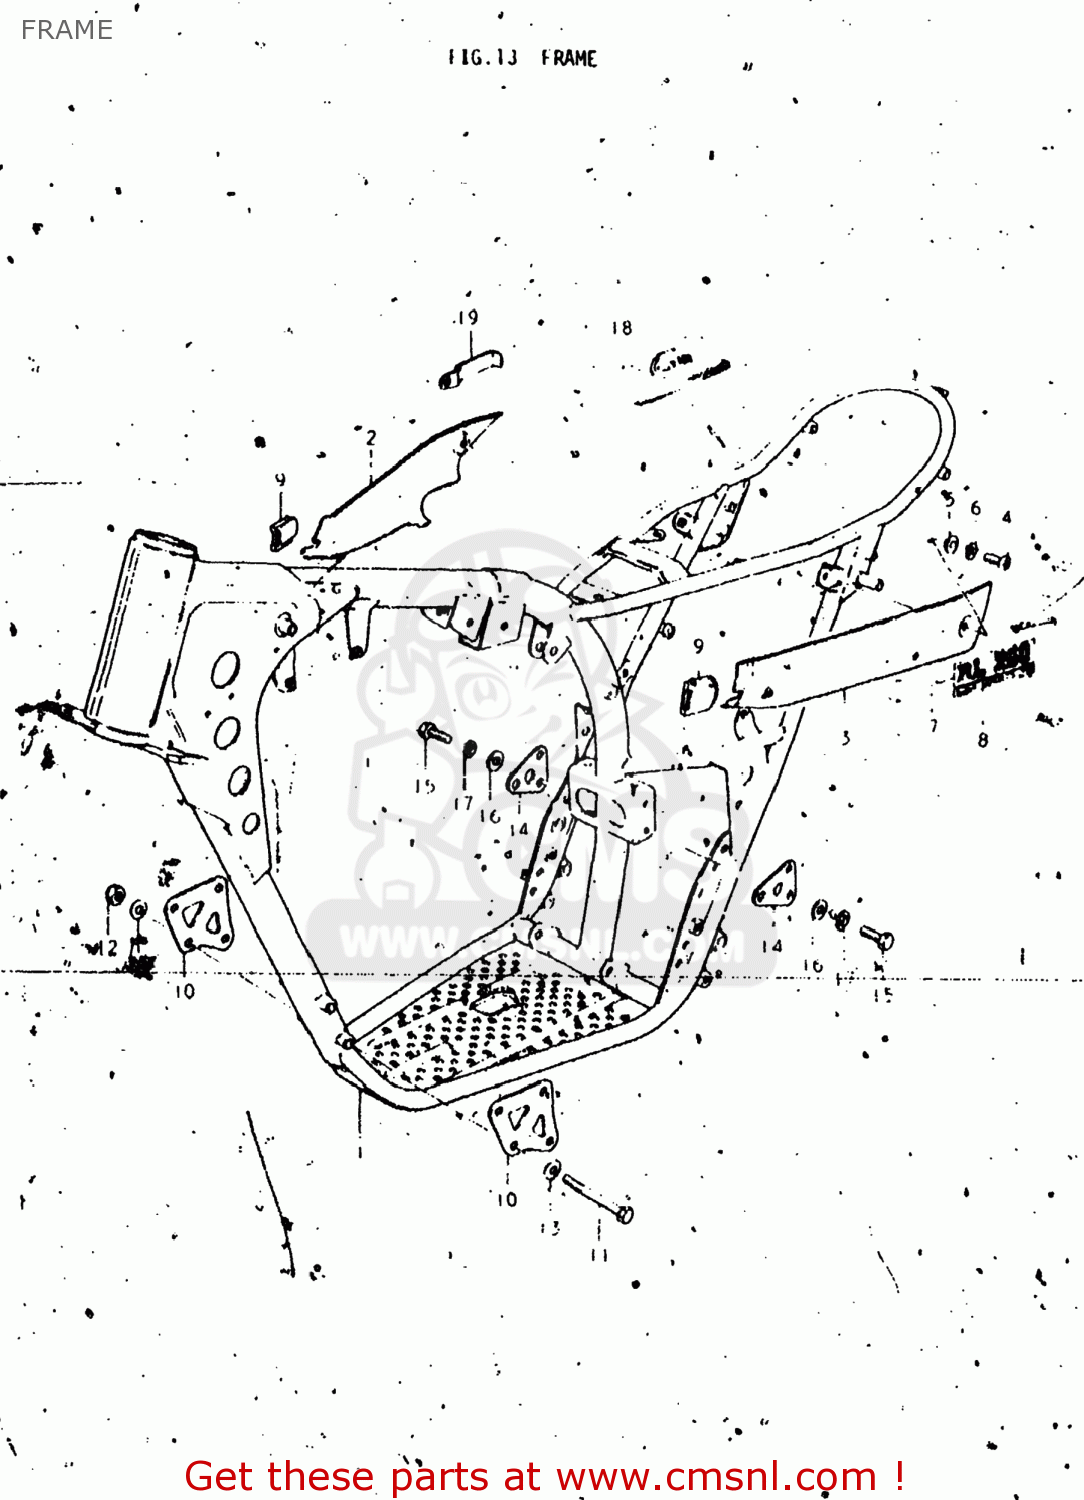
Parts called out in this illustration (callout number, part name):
1	FRAME
2	COVER,FRAME,RIGHT
3	COVER,FRAME,LEFT
4	SCREW 6X12
5	WASHER
6	LOCK WASHER
7	EMBLEM,FRAME COVER
8	LABEL,COMPANY NAME
9	CUSHION,FRAME COVER
10	PLATE,ENGINE MOUNTING
11	BOLT,8X75
12	NUT
13	WASHER
15	BOLT,LOWER
16	WASHER
17	LOCK WASHER
19	CLAMP
